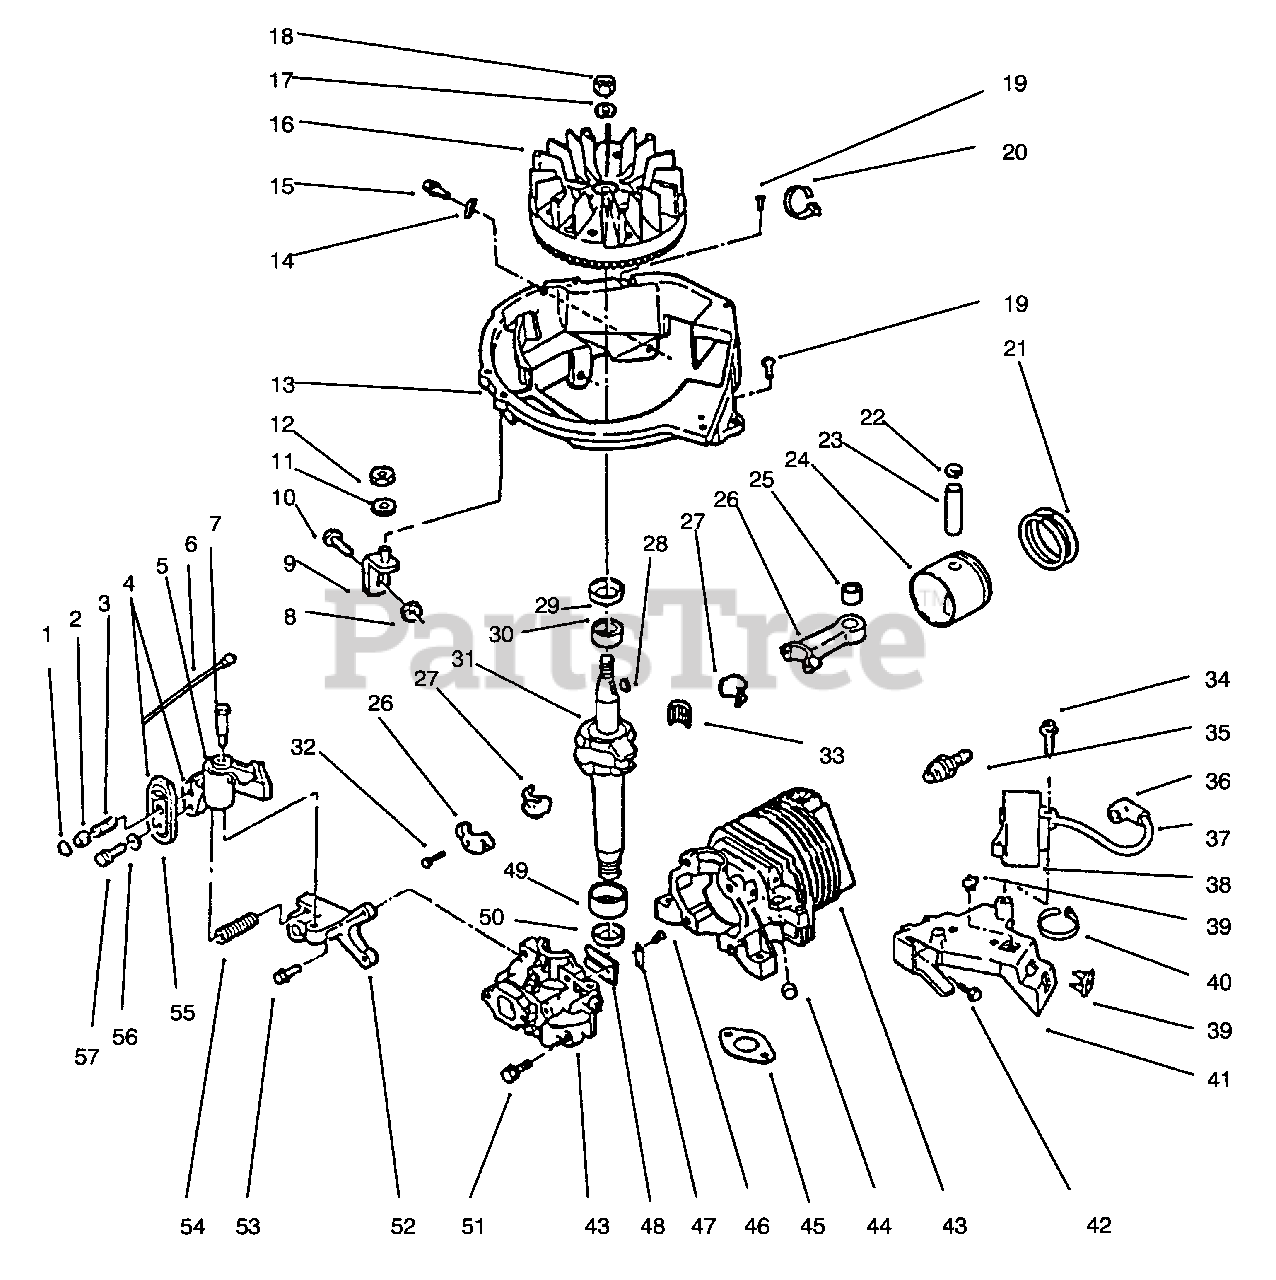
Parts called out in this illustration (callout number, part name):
1	Retainer
2	Actuator-Brake Lever
3	Spring-Cable, Return
4	Switch Assembly (Incl. Ref. #1, 6, 20, & 56-58)
5	Brake Assembly
6	Wire Lead
7	Bolt-Shoulder
9	Brace Assembly
13	Shroud-Base
14	"J"Clip
16	Flywheel Assembly
17	Washer-Lock
18	Nut-Flywheel
20	Tie Strap
21	Set-Ring
22	Ring-Retaining
23	Pin-Wrist
25	Bearing Assembly
26	Connecting Rod Assembly (Incl. Ref. #25, 27,32 & 33)
27	Liner-Pair
28	Key-Flywheel
29	Seal-Oil
30	Bearing-Main
31	Crankshaft
33	Set-Needle Bearing
34	Screw
35	Spark Plug
36	Cover-Terminal
37	Wire Lead & Cover Assy. (Incl. Ref. # 36)
38	C.D. Ignition Module (Incl. Ref. #36, 37)
39	Grommet
40	Tie Strap
41	Bracket-C.D.
43	Cylinder & Crankcase Cover Assembly (Incl.Ref.# 46-48,51 & 53)
45	Gasket-Exhaust
47	Plate-Reed
49	Bearing-Main
50	Seal-Oil
52	Bracket-Brake
54	Spring-Brake
55	Case Assembly
56	Washer
57	Screw
